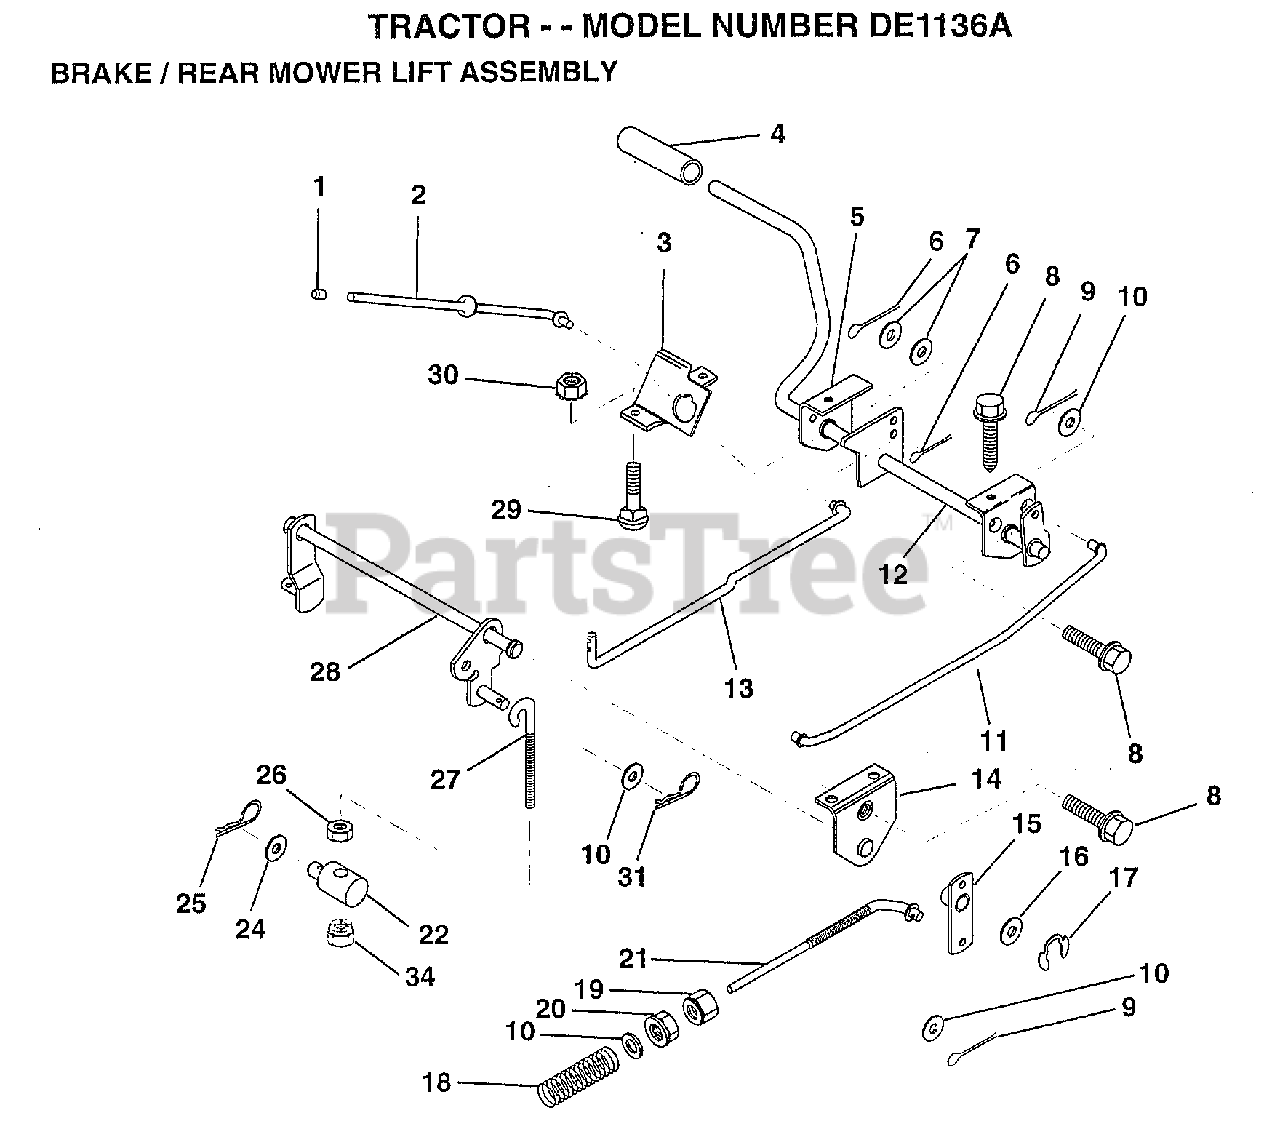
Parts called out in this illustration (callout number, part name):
1	PLUNGER CAP T
2	"ROD,PARK BRAKE"
3	"BRKT,PARK BRAKE"
4	FOOT PEDAL COVER
5	"BRKT,CLU PEDAL LH"
7	WASHER
8	SCREW LT
9	COTTER PIN
10	WASHER
11	"ROD,FRT BRAKE"
12	PEDAL ASM CL/BK36
13	"ROD,CLUTCH"
14	"BRKT,LIFT SHAFT"
15	PVT BRAKE ARM ASM
16	WASHER T
17	KLIP RING
18	SPRING ROD BRAKE
19	NUT
20	NUT
22	TRUNNION.LIFT.
24	WASHER
25	SPRING.RETAINER
26	LOCKNUT
27	"LINK, MOWER REAR"
28	LIFT ASM MOW REAR
31	RETAINER.SPRING
